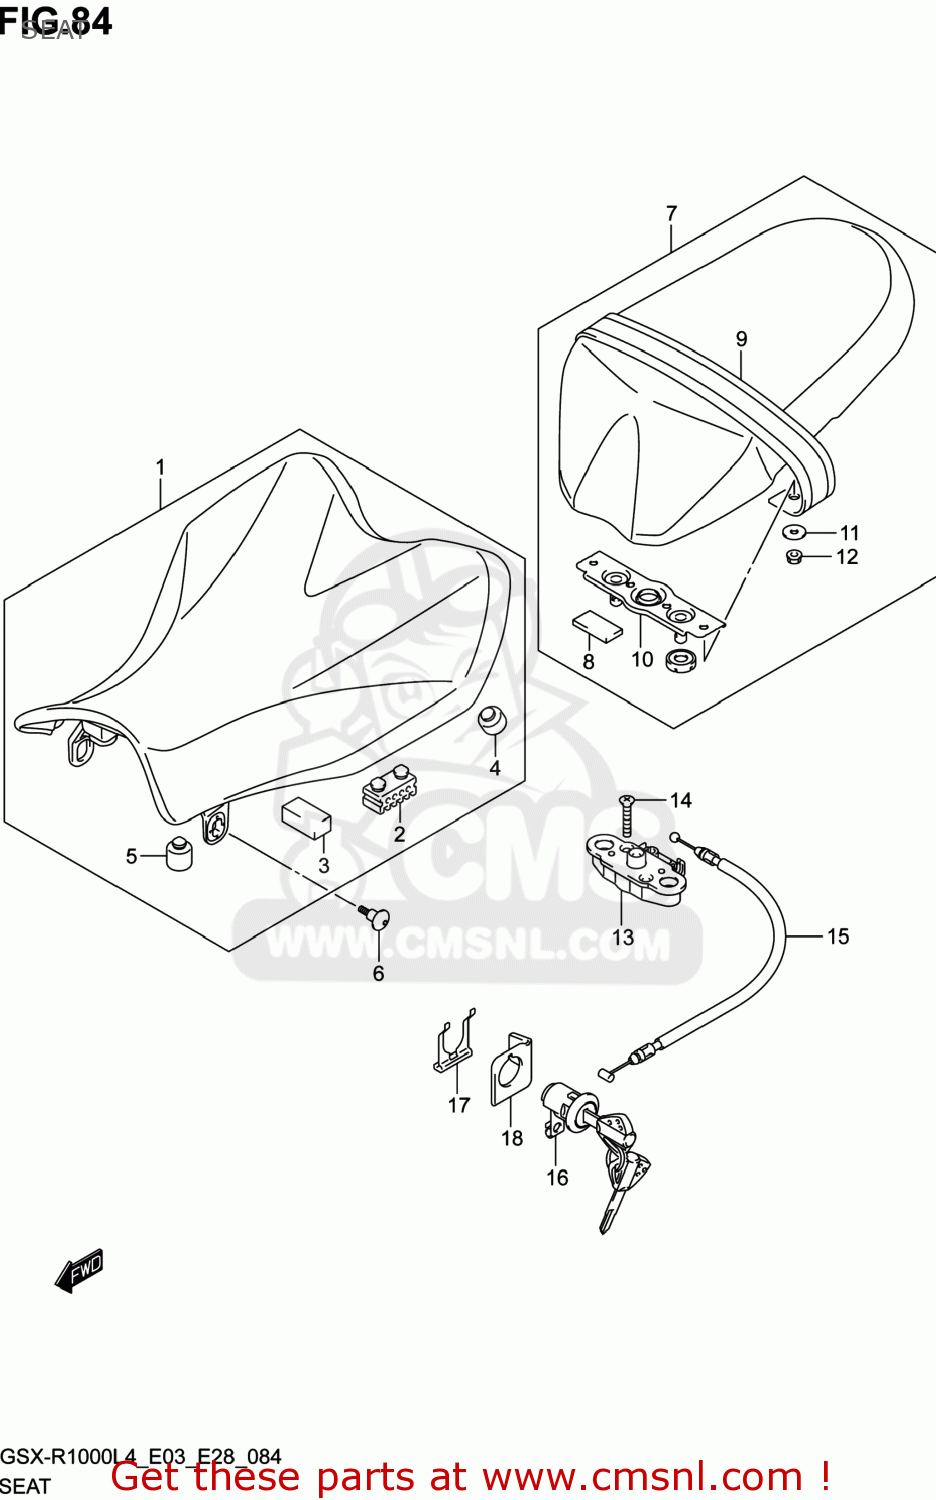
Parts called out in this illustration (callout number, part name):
1	SEAT ASSY
2	CUSHION,SIDE
3	CUSHION,FR(20X40X15)
4	CUSHION
5	CUSHION
6	BOLT(6X20)
7	SEAT ASSY,PILLION
8	CUSHION,FR(20X40X15)
9	BAND ASSY,SEAT(BLACK)
10	STRIKER
11	WASHER(6.5X20X1.6)
12	NUT
13	BRACKET,SEAT SUPPORT
14	SCREW
15	CABLE,SEAT LOCK
16	LOCK SET,SEAT
17	PLATE,SEAT LOCK ASSY
18	GUIDE,SEAT LOCK CABLE
